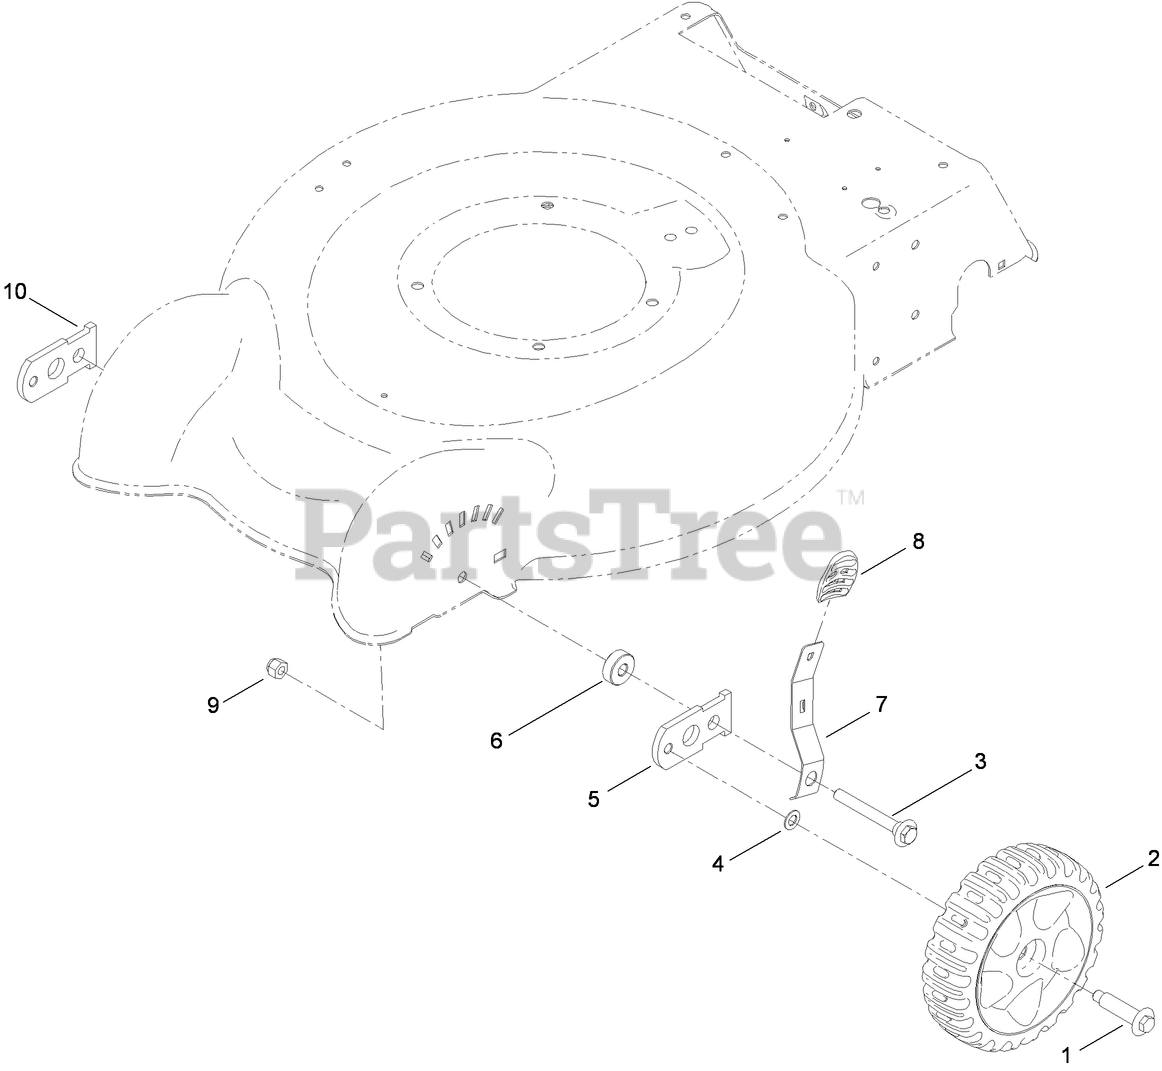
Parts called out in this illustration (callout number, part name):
1	BOLT-SHOULDER
2	7 INCH WHEEL AND TIRE ASM
3	BOLT-SHOULDER
4	WASHER
5	ARM-PIVOT, RH
6	SPACER-ARM, PIVOT
7	ARM-SPRING, FRONT
8	KNOB-LEVER, HOC
9	NUT-LOCK, NI
10	ARM-PIVOT, LH
